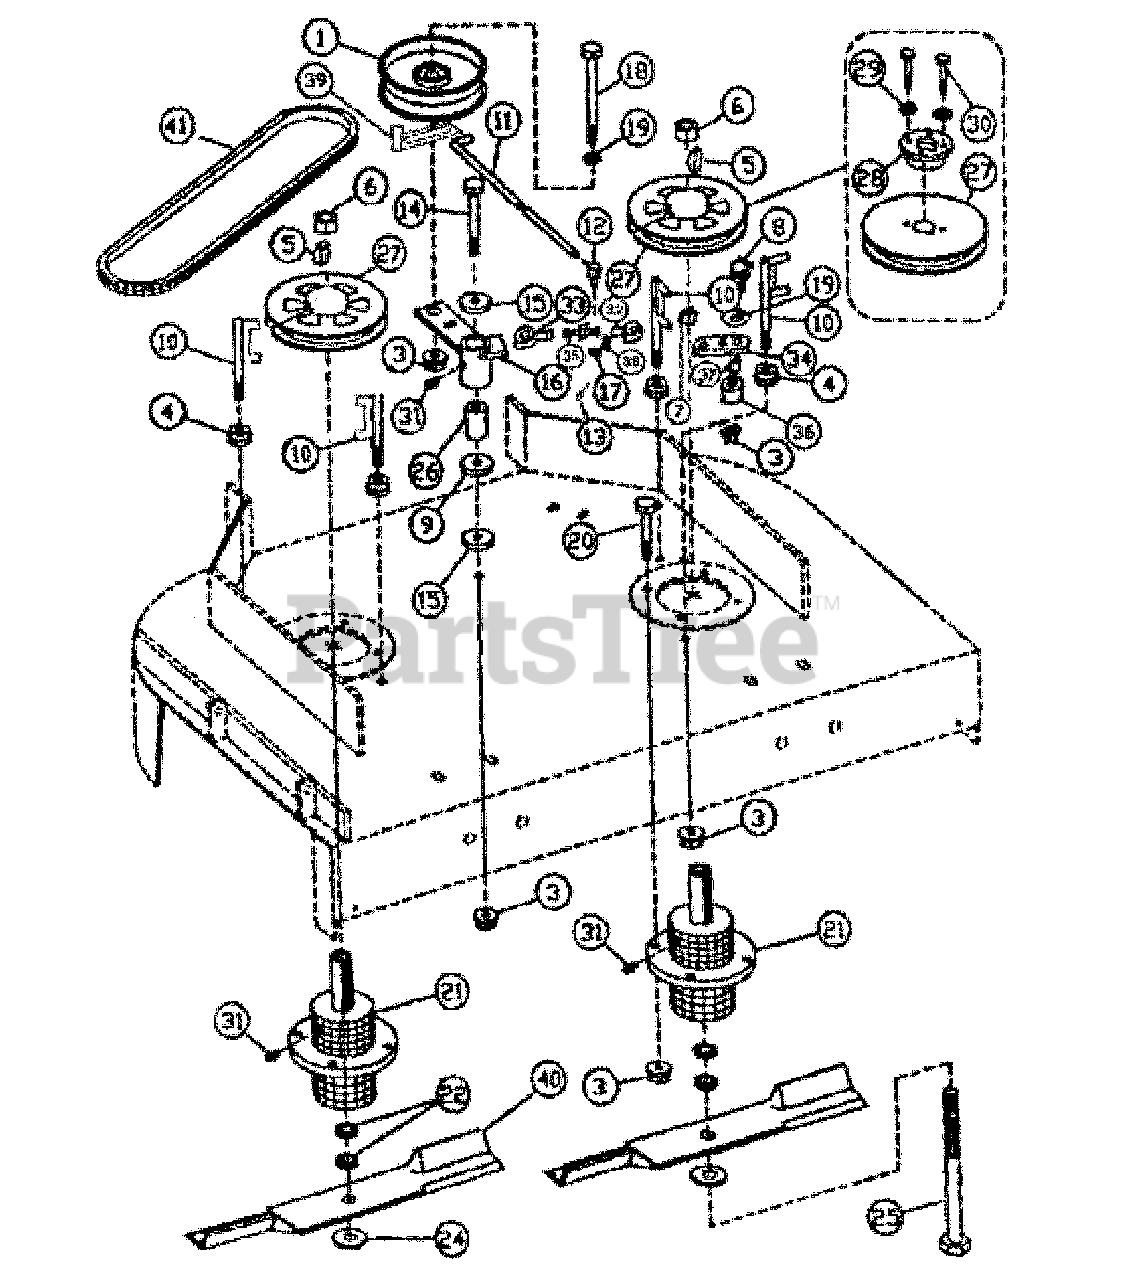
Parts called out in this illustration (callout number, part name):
1	100-013 IDLER PULLEY
3	200-006 NYLON NUT M10
4	200-016 NUT FLANGE M10
5	100-014 KEY 6.35`6`50
6	200-017 NEX NUT M16`1.5
7	200-018 HEX BOLT M10-35
8	200-019 HEX BOLT M10-40
9	100-015 WASHER 2`26ID
12	100-018 SWIVEL
13	200-014 COTTER PIN 2`20
14	M10X1.5X70 HHB GR8.8
15	100-019 WASHER
16	100-020 IDLER ARM WLDT.
17	5/16STD FLAT WASHER.
18	200-022 HEX BOLT M10`65
19	WASHER, 3/8 STD FLAT
20	200-018 HEX BOLT M10-35
21	100-021 CUTTING HOUSE AS
22	100-022 SPACER 6
24	100-023 WASHER
25	200-023 BOLT M16`1.5`245
26	100-024 PIVOT HUB
27	100-025 PULLEY SINGLE
28	100-026 H-BUSHING
29	5/16HELICAL L-WASHER
30	M8X1.25X30MM HHB
31	GREASE FTG (10 PACK) 200-026
32	100-027 ROD END RH
34	100-029 LINK IDLER ARM
35	100-030 TURN BUCKLE ROD
36	100-031 SPACER 12
37	100-032 LINK BUSHING
39	100-033 BELT GUIDE
40	BLD 36` - WALKABOUT
41	136-004 BELT 36`ENG-BLD
